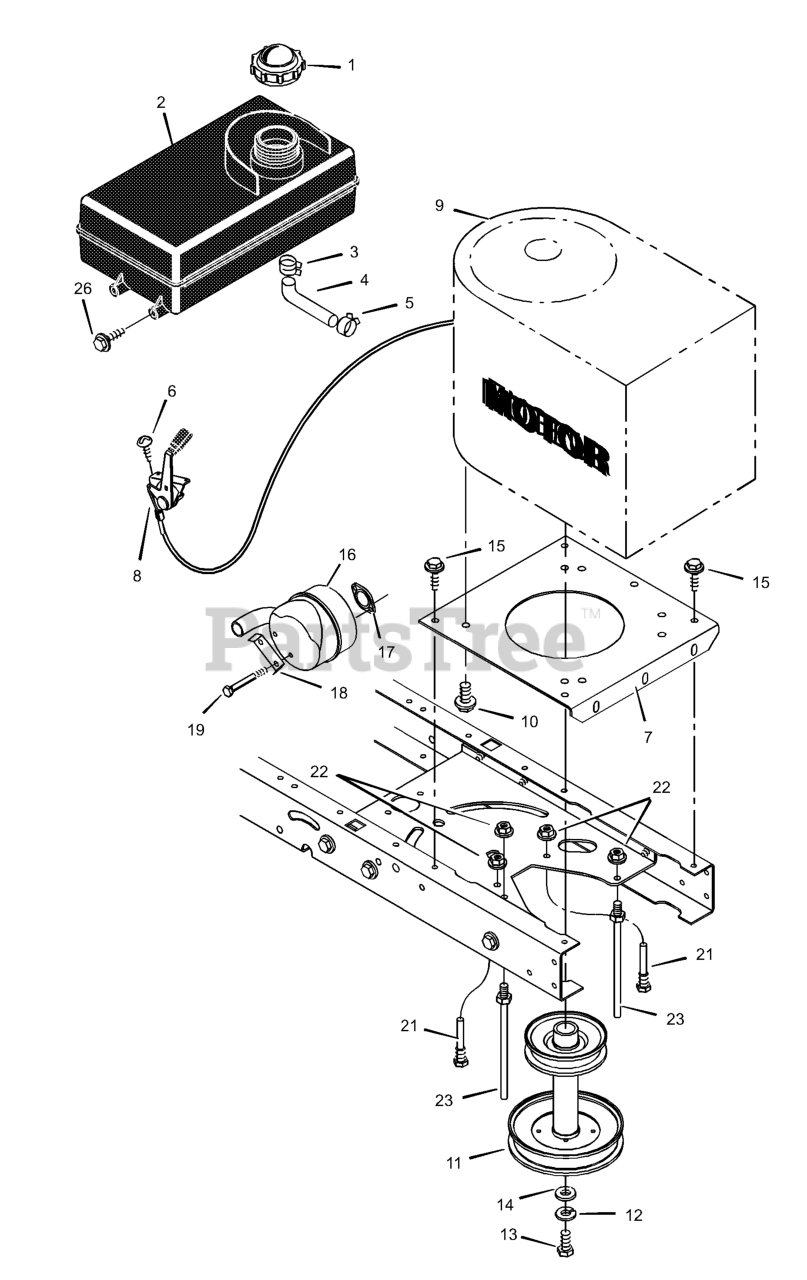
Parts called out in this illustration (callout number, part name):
1	Fuel Cap
2	Fuel Tank
3	Hose Clamp
4	Fuel Line (Must cut to length)
5	Hose Clamp
7	Plate, Engine
8	Throttle Control
9	Engine *
10	Bolt, Engine Mount
11	STACK PULLEY ASSEMBLY
12	Lockwasher
13	Perno de cabeza hexagonal
16	Muffler
17	GASKET, Exhaust
18	Lock, Screw
21	Guide, Belt
22	Nut, Flange
23	Guide, Belt
